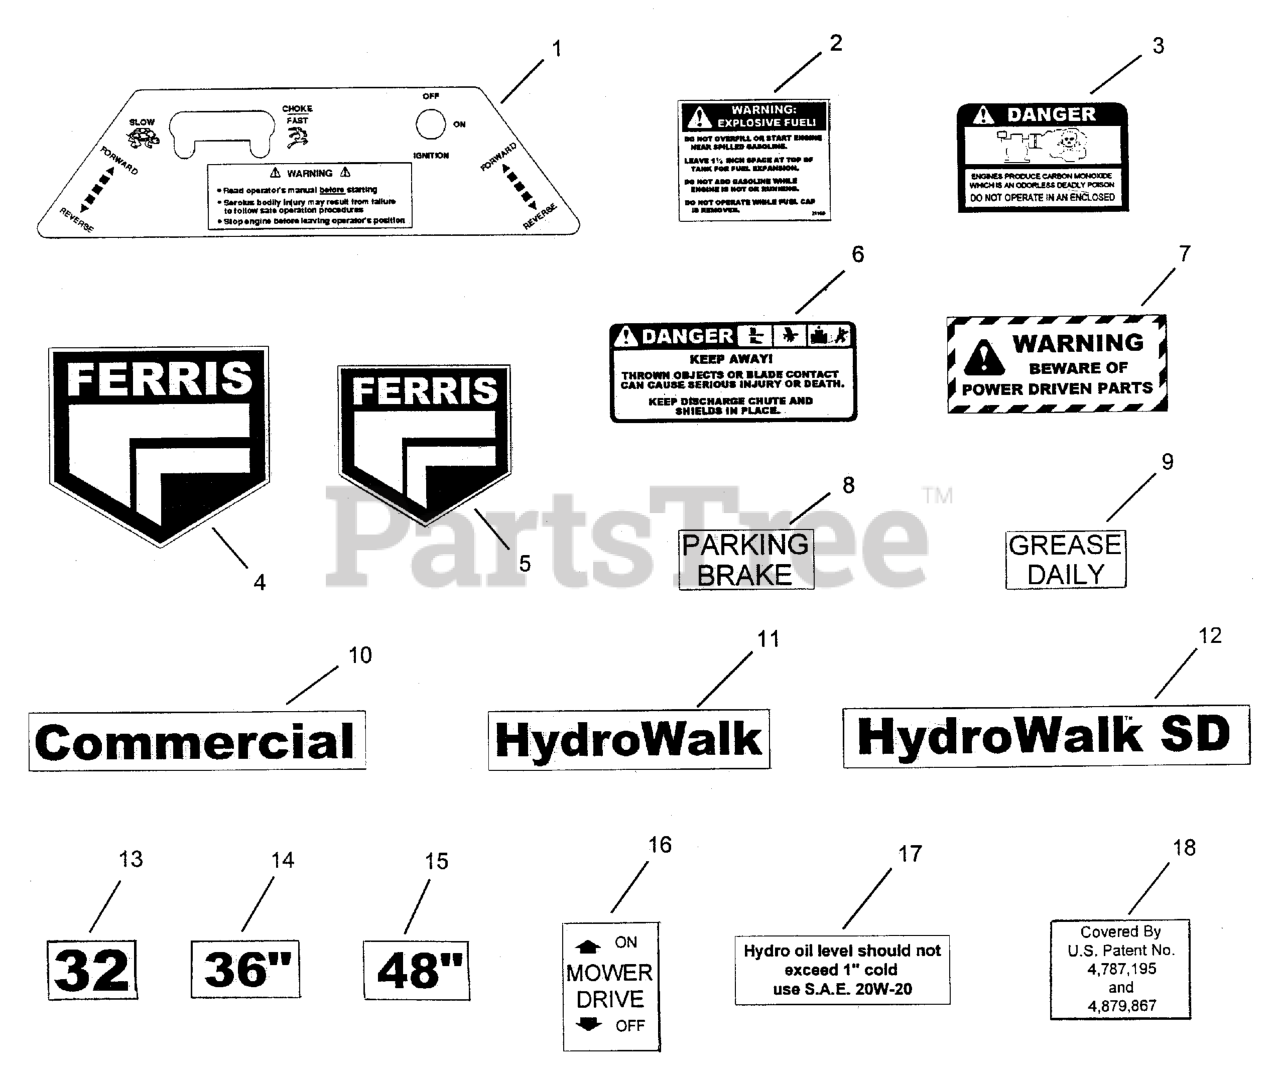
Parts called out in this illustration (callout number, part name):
1	DECAL, HW Dash
2	DECAL, EXPLOSIVE FUEL
3	DECAL, Danger, Carbon Monoxide
4	DECAL, Ferris Logo, 10-3/4"
5	DECAL, FERRIS LOGO, 9-3/8
6	DECAL, DANGER DO NOT OPERATE W/O DEFLECT
7	DECAL, WARNING Operation
8	DECAL, Parking Brake
9	DECAL, Grease Daily
10	DECAL, Commercial
11	DECAL, HydroWalk, Word
12	DECAL, HydroWalk SD
13	DECAL, 32"
14	DECAL, 36"
15	DECAL, 48
16	DECAL, Mower Drive On / Off
17	DECAL, Hydro Oil Level
18	DECAL, Walker Patent Number
